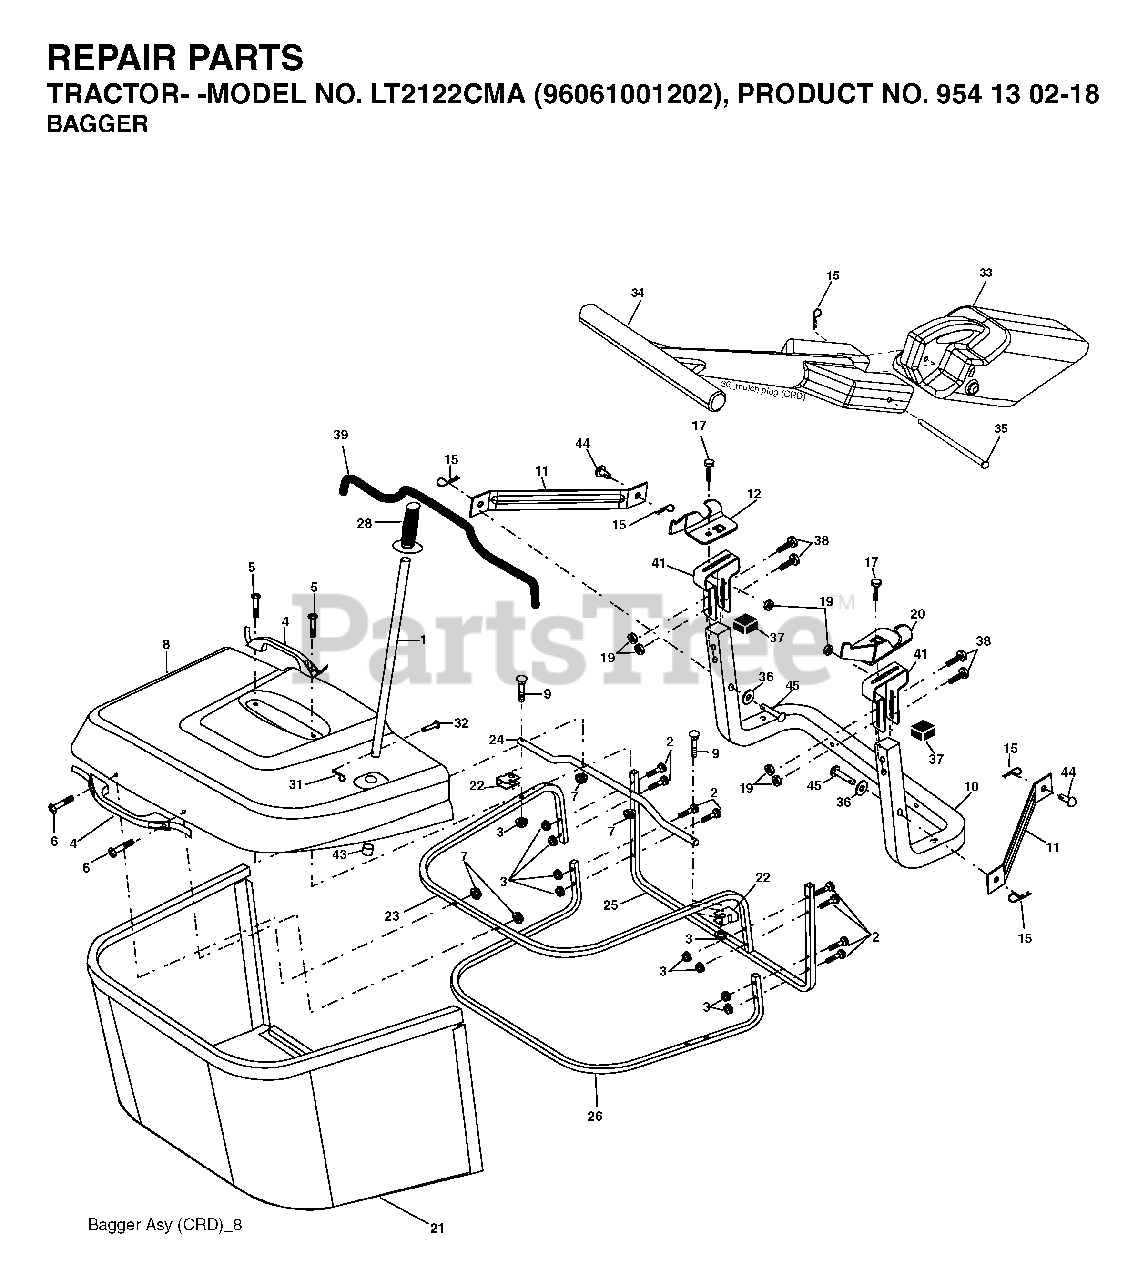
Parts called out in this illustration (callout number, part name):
1	TUBE HANDLE
3	NUT T
5	SCREW.PAN.HEAD
11	BRACKET
15	RETAINER-SPRNG RB
17	BOLT
19	NUT LOCK HEX FLANGE 5/16-18
20	BRKT.PIVOT.RH.CRD
21	GRASS BAG
22	BRACKET
23	TUBE
24	TUBE
26	TUBE
28	GRIP.HANDLE.BLACK
31	RETAINER CLIP
32	RIVET,DRILLED
33	MULCH PLUG, CTH150
35	PIN
38	BOLT.5/16-18X2.5
41	BRKT, BAGGER
42	NUT.71038.31-18.HEX.NYLOCK
43	PLUG, TUBING END
